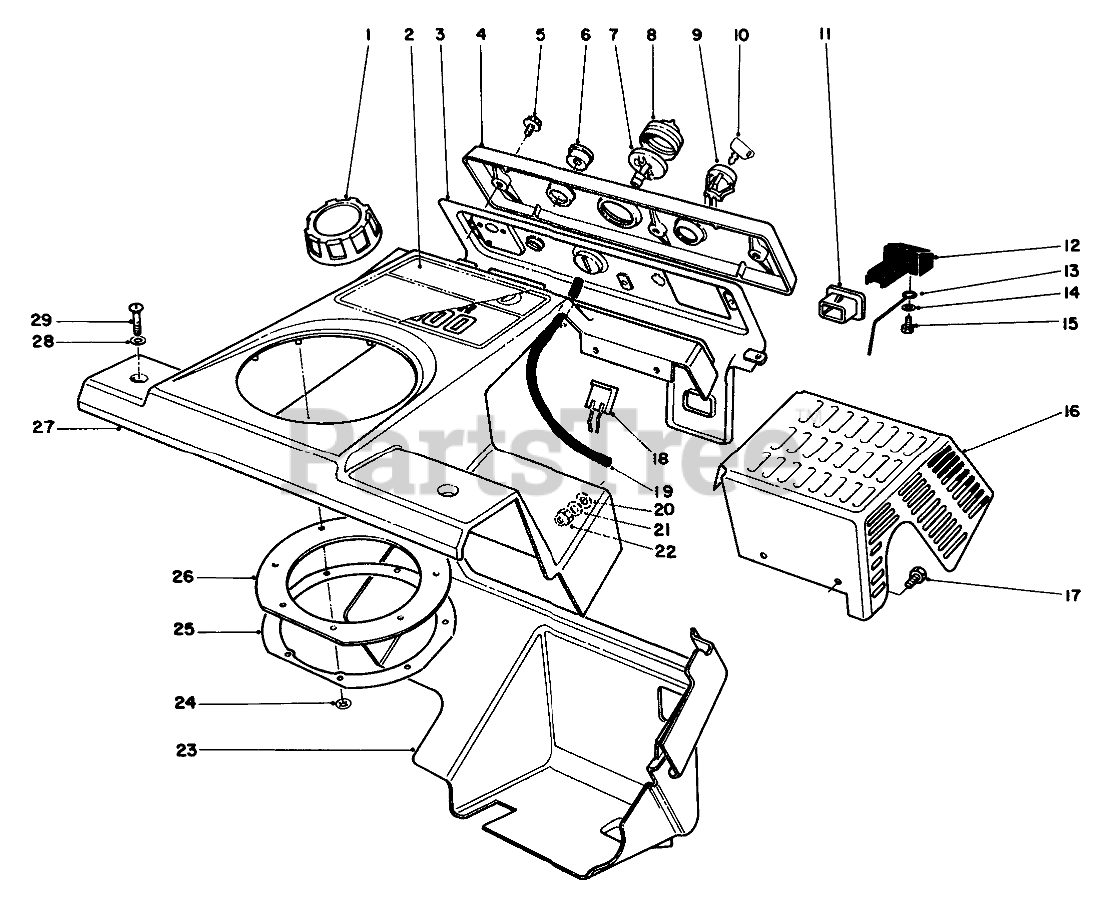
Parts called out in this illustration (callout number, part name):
1	CAP-FUEL ASM
2	Decal-CCR-2000
3	Control Panel Assembly (Incl. Ref. #6-8 & 11)
4	CONTROL NAMEPLATE
5	SCREW
6	GUIDE-ROPE, STARTER
7	BODY-PRIMER
8	Bulb Primer
9	SWITCH
10	KEY-IGNITION
11	FITTING
12	CONTROL-CHOKE
13	Linkage-Choke
14	Washer
15	#8 X .625" PHILPS PAN H
16	Wa-Shield
17	SCREW-SHH
18	CONNECTOR-BODY
19	PRIMER HOSE
20	WASHER
21	WASHER-FLAT
22	NUT-LOCK, SIDE
23	Shroud-Lower
24	PALNUT
25	Retainer-Chute Seal
26	SEAL-CHUTE
27	Upper Shroud Assembly (Incl. Ref. #2 & 24-26)
28	WASHER-FLAT
29	SCREW-PPH
